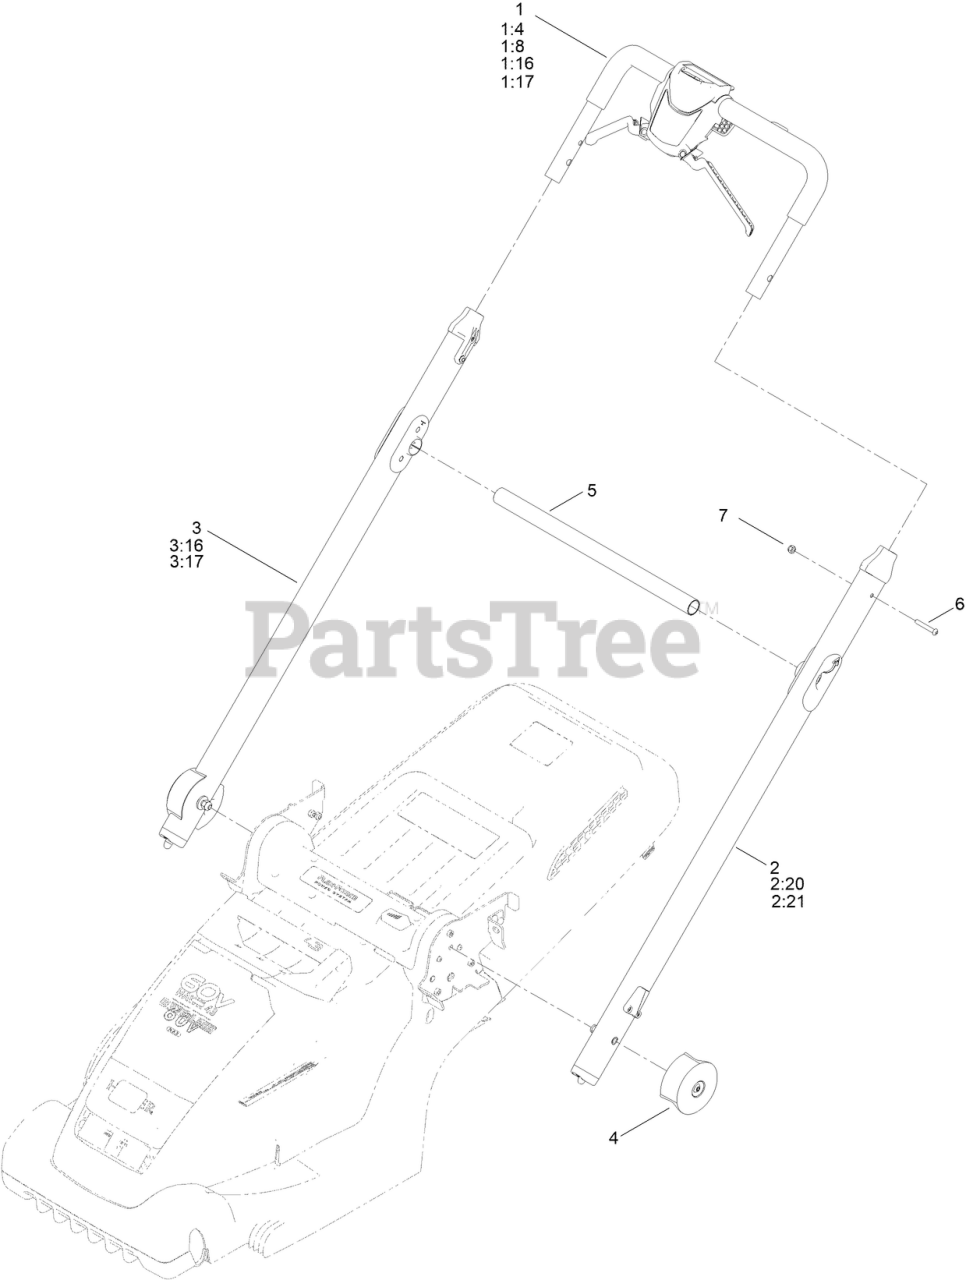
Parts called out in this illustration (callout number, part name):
1	CONTROL LEVER ASM, PROPELLED
1:4	TOP BUTTON KIT
1:8	UPPER LEVER KIT (43)
1:16	LOWER LEVER KIT
1:17	SPEED CONTROLLER WHEEL KIT
2	HANDLEBAR ASM, LH
2:20	HANDLEBAR BRACE - INNER
2:21	HANDLEBAR BRACE, OUTER
3	HANDLEBAR ASM, RH
3:16	HANDLEBAR BRACE - INNER
3:17	HANDLEBAR BRACE, OUTER
4	HANDLEBAR END CAP
5	BRACE, HANDLEBAR RELEASE
6	BOLT, M6X40
7	NUT, M6, NYLOC
